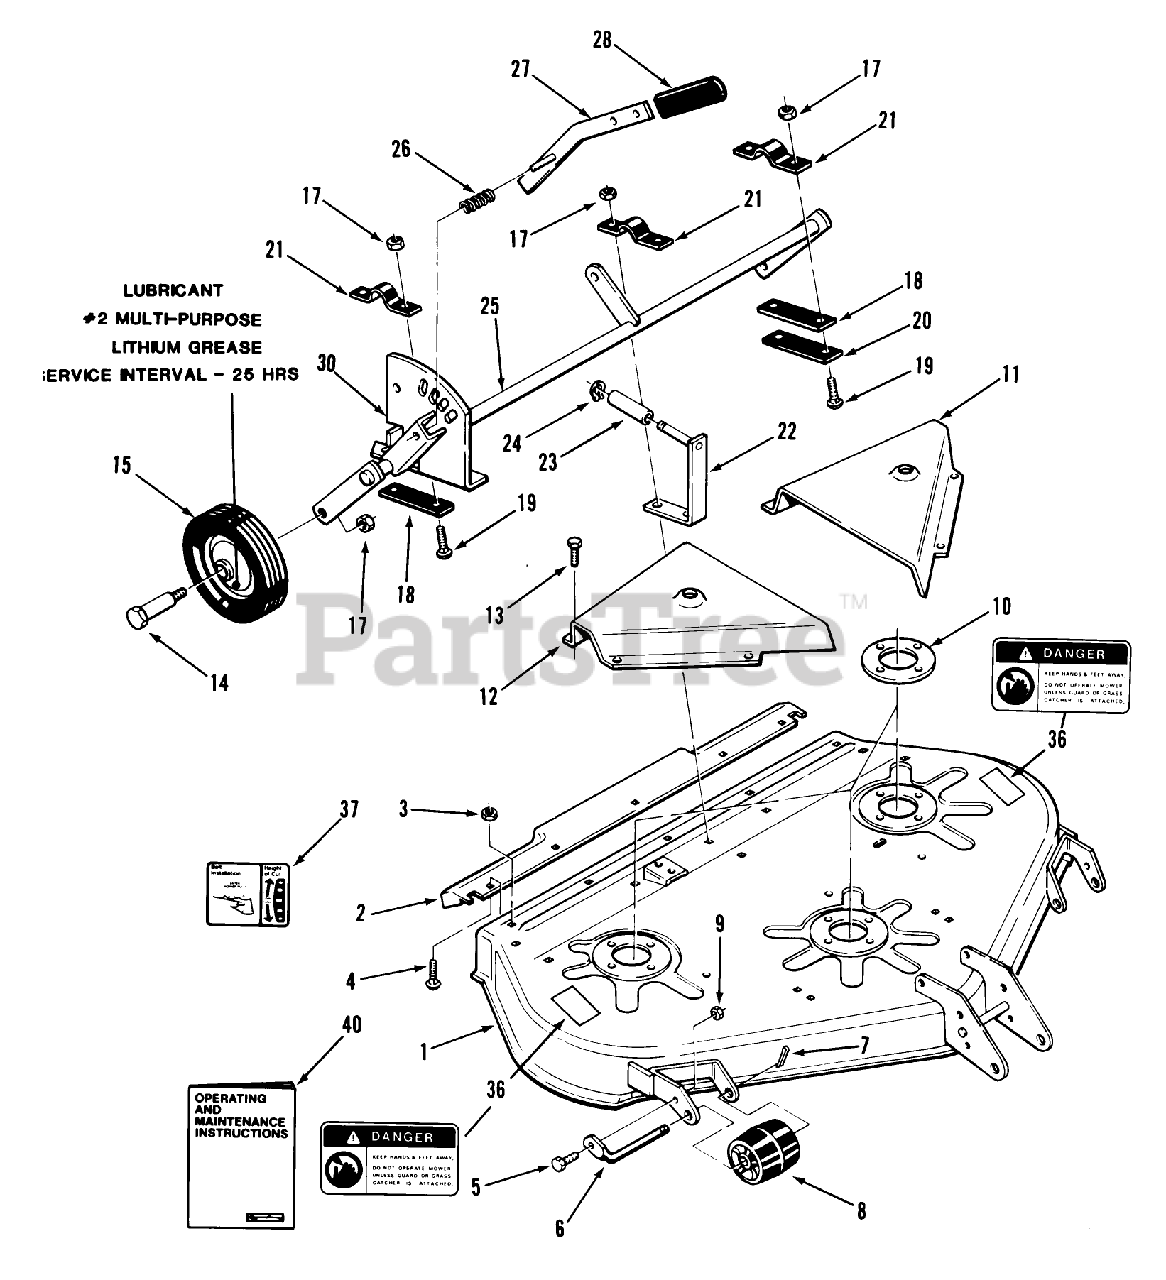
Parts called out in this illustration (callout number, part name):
6	ROLLER-SHAFT
10	PLATE-SPINDLE
13	Bolt
14	BOLT-SHOULDER
15	WHEEL
18	STRAP 1/16 *B
21	CLAMP
26	SPRING-COMPRESSION
37	DECAL-HEIGHT BELT
40	Operating Maintenance Instructions
